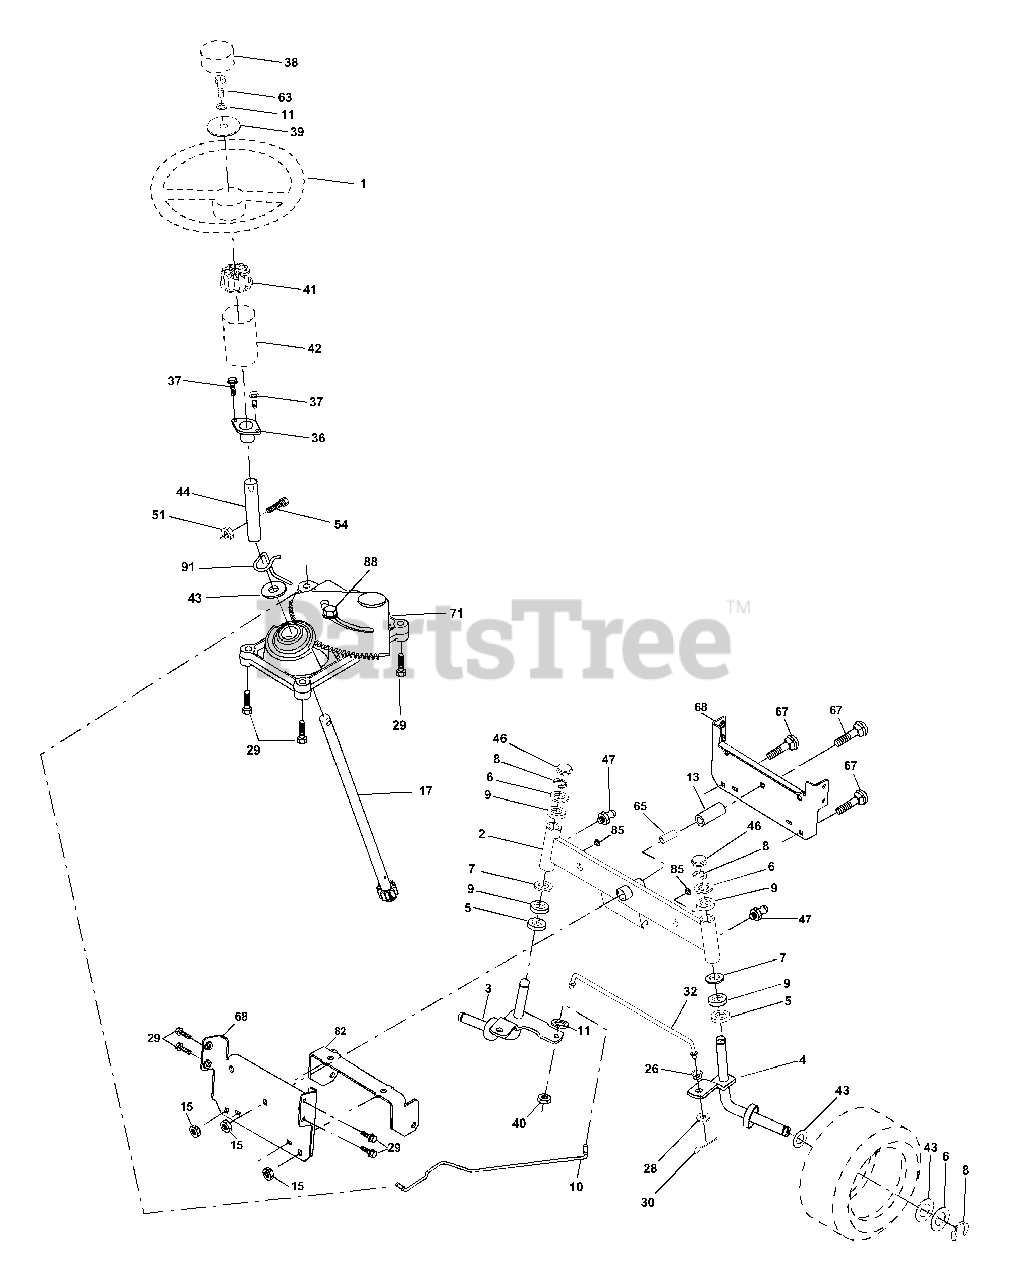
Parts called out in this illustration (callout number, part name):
1	Steering Wheel
2	Front Axle Asm
3	Spindle Asm Lh
4	Spindle Asm Rh
5	Washer Thrust .75 x 1.230
6	Washer 25/32 x 1-5/8 x 16 Ga.
7	Washer 27/32 x 1-1/4 x 16 Ga.
8	Ring Klip #T5304-75
9	Bearing Col Strg Blk
10	Draglink
11	Washer Lock Hvy Hlcl Spr 3/8
13	Spacer Brg Axle Front
15	Nut Hexflange Lock
17	Shaft Asm Strg
26	Bushing LInk Drag Blk LR
28	Washer 13/32 x 7/8 x 16 Ga.
29	Screw 3/8-16 x 3/4
30	Pin
32	Rod Tie Wire Form 19.75 Mech
36	Bushing Strg. 5/8 ID Dash
37	Screw
38	Insert, Steering Wheel
39	Washer 13/32 x 2-3/8 x 12 Ga.
40	Nut Lock Center 3/8-24
41	Adaptor Wheel Strg.
42	Boot Steering Dash P/L MTL Blk
43	Washer 25/32 x 1-1/4 x 16 Ga.
44	Extension Steering Non-adjust
46	Cap Spindle Fr Top Blk
47	Fitting Grease
51	Nut Lock Hx W/Ins 5/16-18unc
54	Bolt Fin Hex 5/16-18unc
63	Bolt Fin Hex 3/8-16unc x 1 Gr. 5
65	Spacer Axle
67	Bolt Rdhd Sqnk 3/8-16 x 2-1/4
68	Brace Axle
71	Steering Asm.
82	Bracket Susp Chasis Front
85	Fastner Christmas Tree
88	Bolt Shoulder 7/16-20
91	Clip Steering
